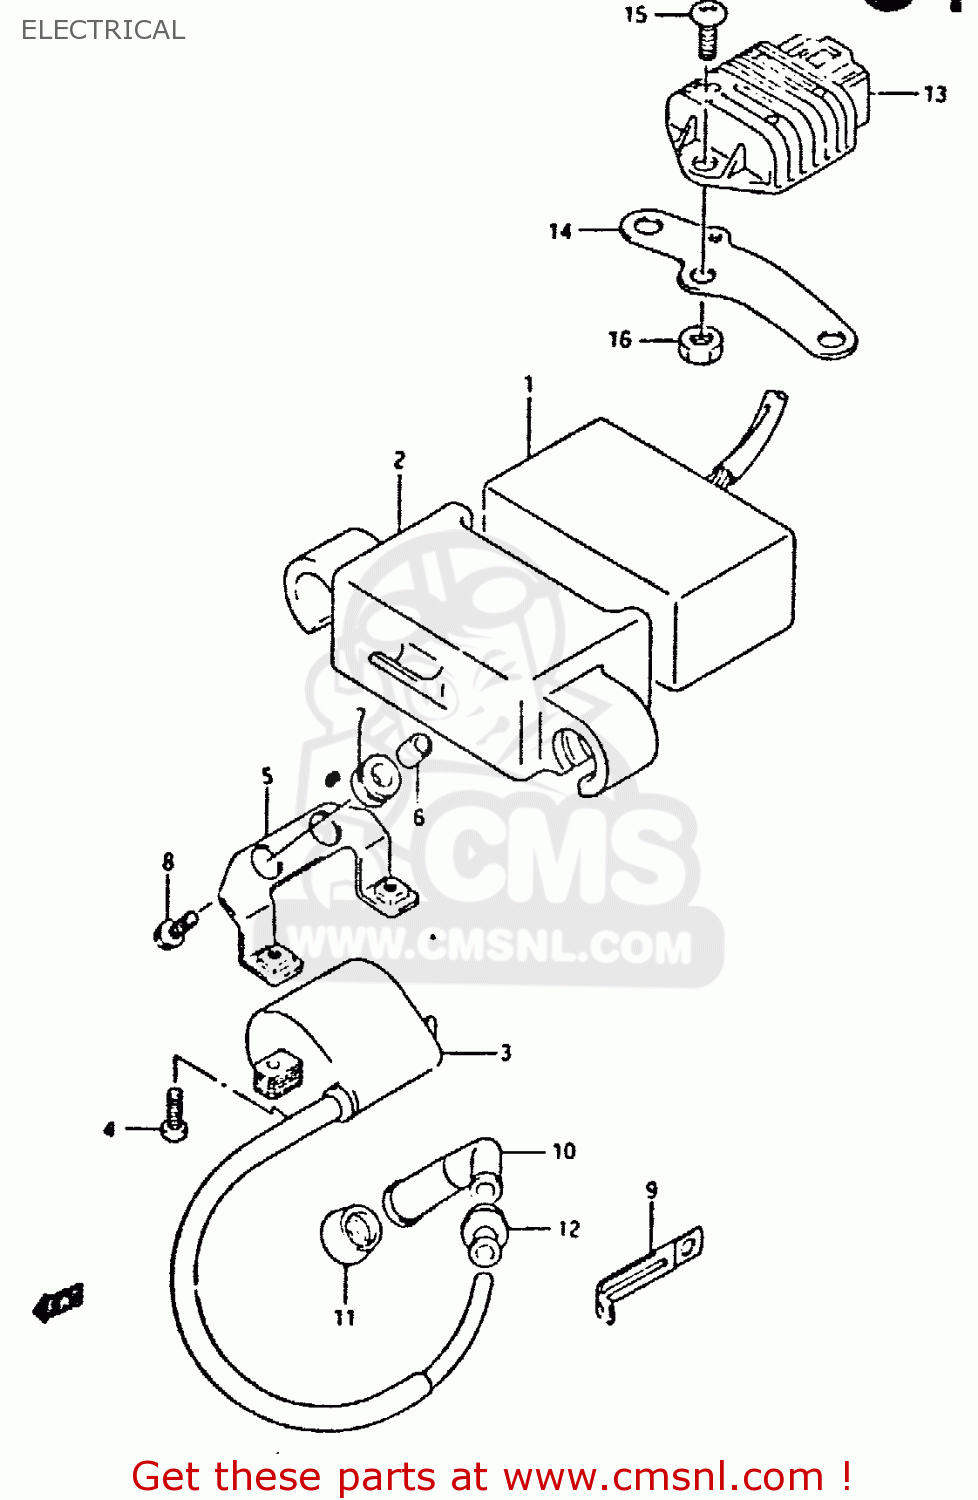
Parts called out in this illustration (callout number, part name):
1	CDI UNIT
2	CUSHION,CDI UNIT
3	COIL ASSY,IGNITION
4	SCREW
5	BRACKET,IGNITION COIL
6	SPACER (6.3X9.1X6.7)
7	CUSHION
8	BOLT
9	CLAMP(L:45)
10	CAP,SPARK PLUG
11	SEAL,SPARK PLUG
12	SEAL,HIGH TENSION CORD
13	REGULATOR ASSY
14	BRACKET,REGULATOR
15	SCREW
16	NUT
